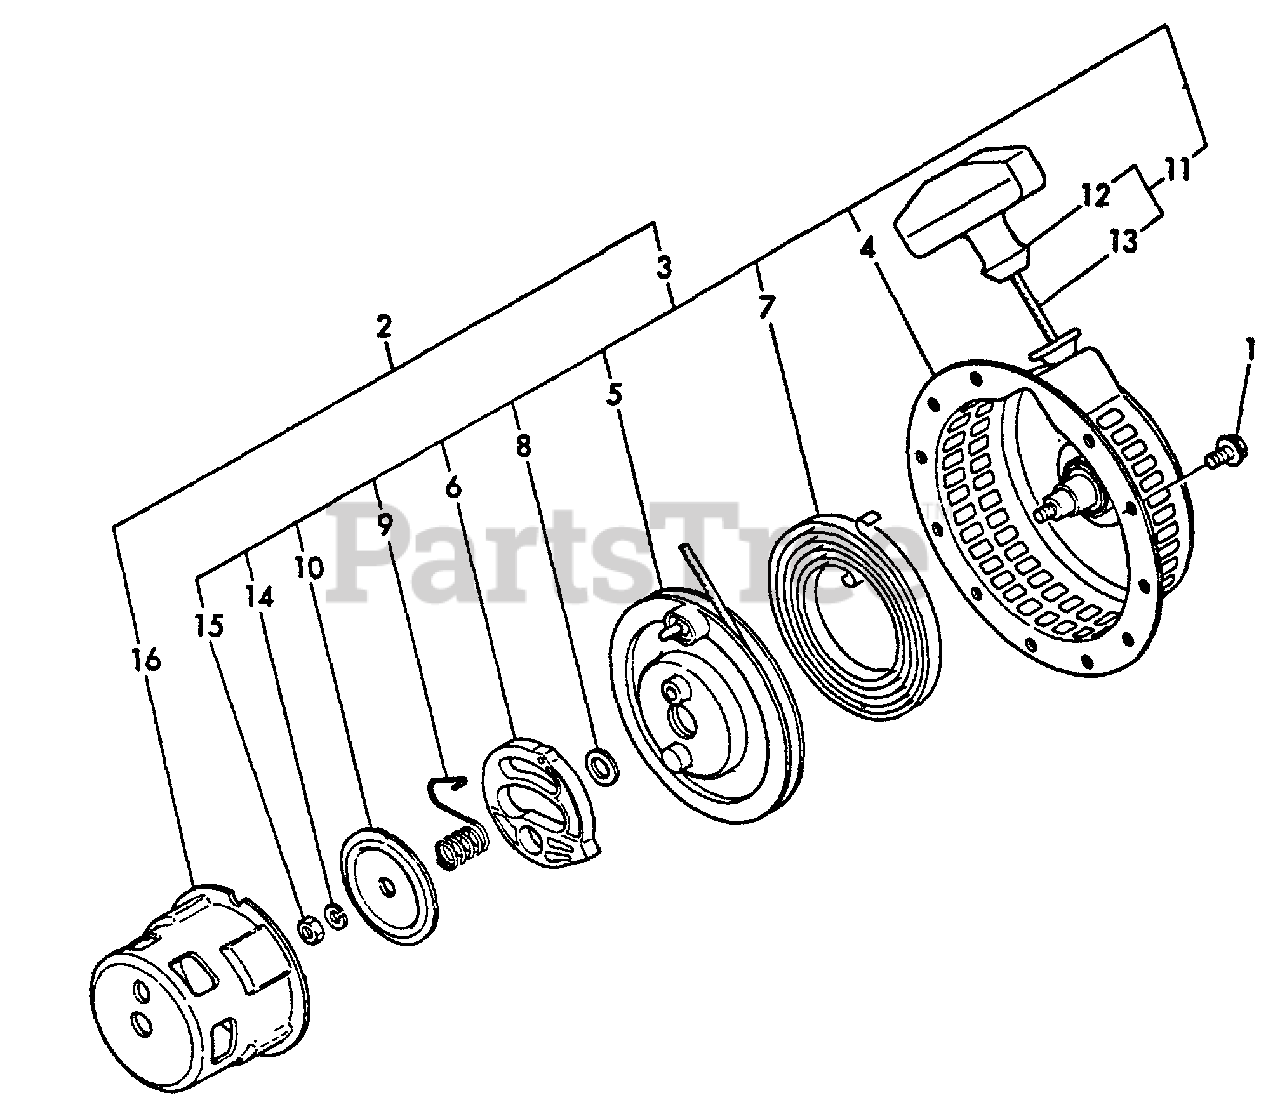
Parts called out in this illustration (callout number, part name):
1	BOLT - 6X12 -- PLATED
2	STARTER ASSY
3	STARTER ASSY
4	CASE, STARTER
5	PULLEY
8	WASHER, THRUST
9	SPRING, FRICTION
10	PLATE, FRICTION
11	STARTER ROPE ASSY
12	GRIP, STARTER
13	ROPE, STARTER
14	LOCKWASHER - 6
15	NUT - 6
16	REEL, ROPE
